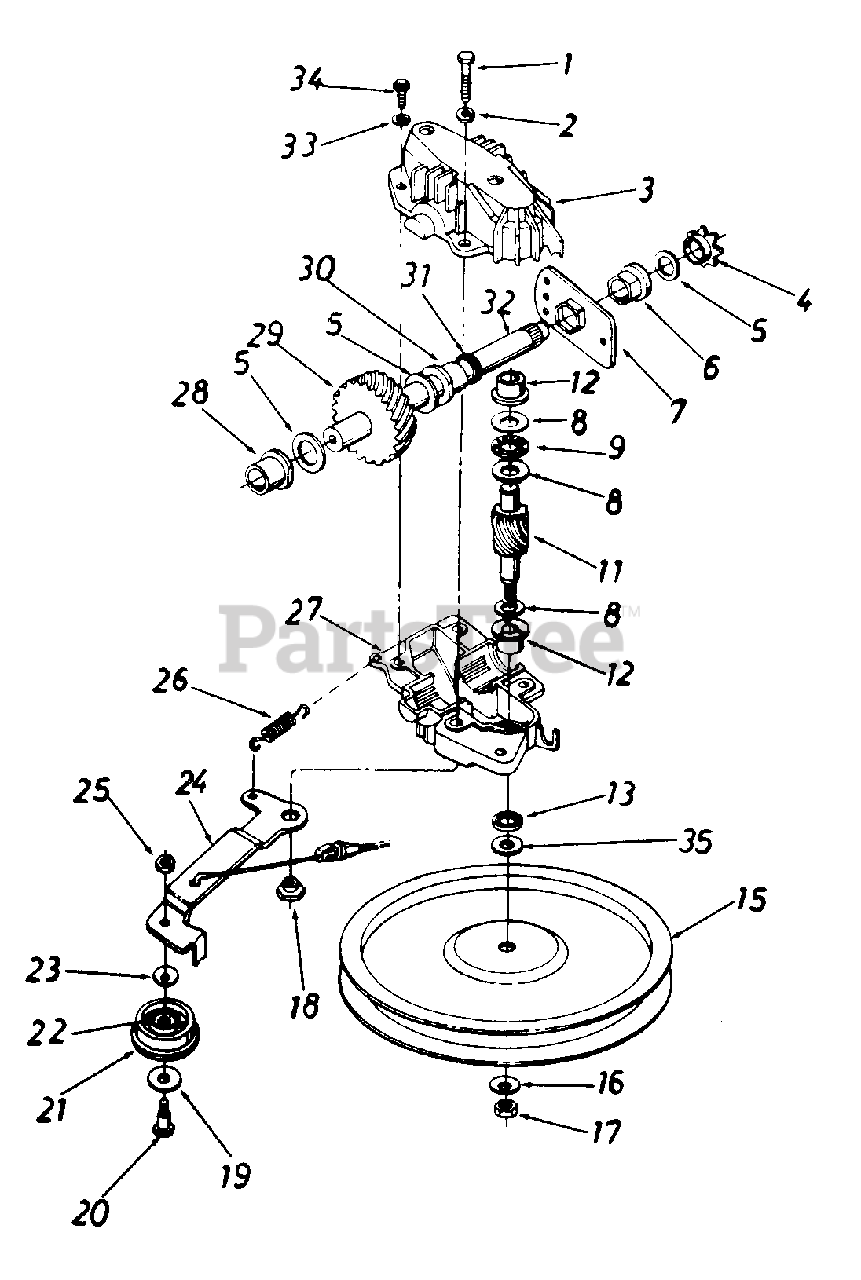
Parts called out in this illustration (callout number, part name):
1	Hex Bolt 1/4-20 x 1.25" Lg.t
2	L-Wash. 1/4" I.D.t
3	Upper Hsg. Half
4	#48 Sprocket 7 Tooth x 1/2 Pitch
5	Fl-Wash. 5/8" I.D. x .030
6	Hex Flange Brg. .631" I.D.
8	Thrust Wash. .382" I.D. x .70" O.D.
9	Thrust Bearing .375" I.D. x .812" O.D.
11	11 Tooth Pinion Shaft
12	Flange Bearing
13	Oil Seal
15	Fl-Pulley 5.06" O.D.
16	Bell-Wash. .265" I.D. x .75"
17	Hex L-Nut 1/4-28 L.H. Thd.
18	Shld. Spacer .375" Dia. x 17"
19	Fl-Wash. .390" I.D. x 1.0"
20	Shld. Bolt .375" Dia. x .40"
21	Fl-Idler Plastic 1.50" Dia.
22	Needle Brg. .375" x .31
23	Bell-Wash. .265" I.D. x .75"
24	Idler Brk t. Ass y
25	Hex Patch L-Nut 1/4-28 Thd.
26	Extension Spring 1.12" Lg.
27	Lower Hsg. Half
28	Flange Bearing .566 Dia.
29	33 Tooth Helical Gear
30	Flange Bearing .629 Dia.
31	Oil Seal .625 Dia.
32	Gear Sprocket Shaft
33	L-Wash. #10 I.D.
34	Hex B-Tap Scr. #10 x .62"
35	Hex Washer .26" x .88"
